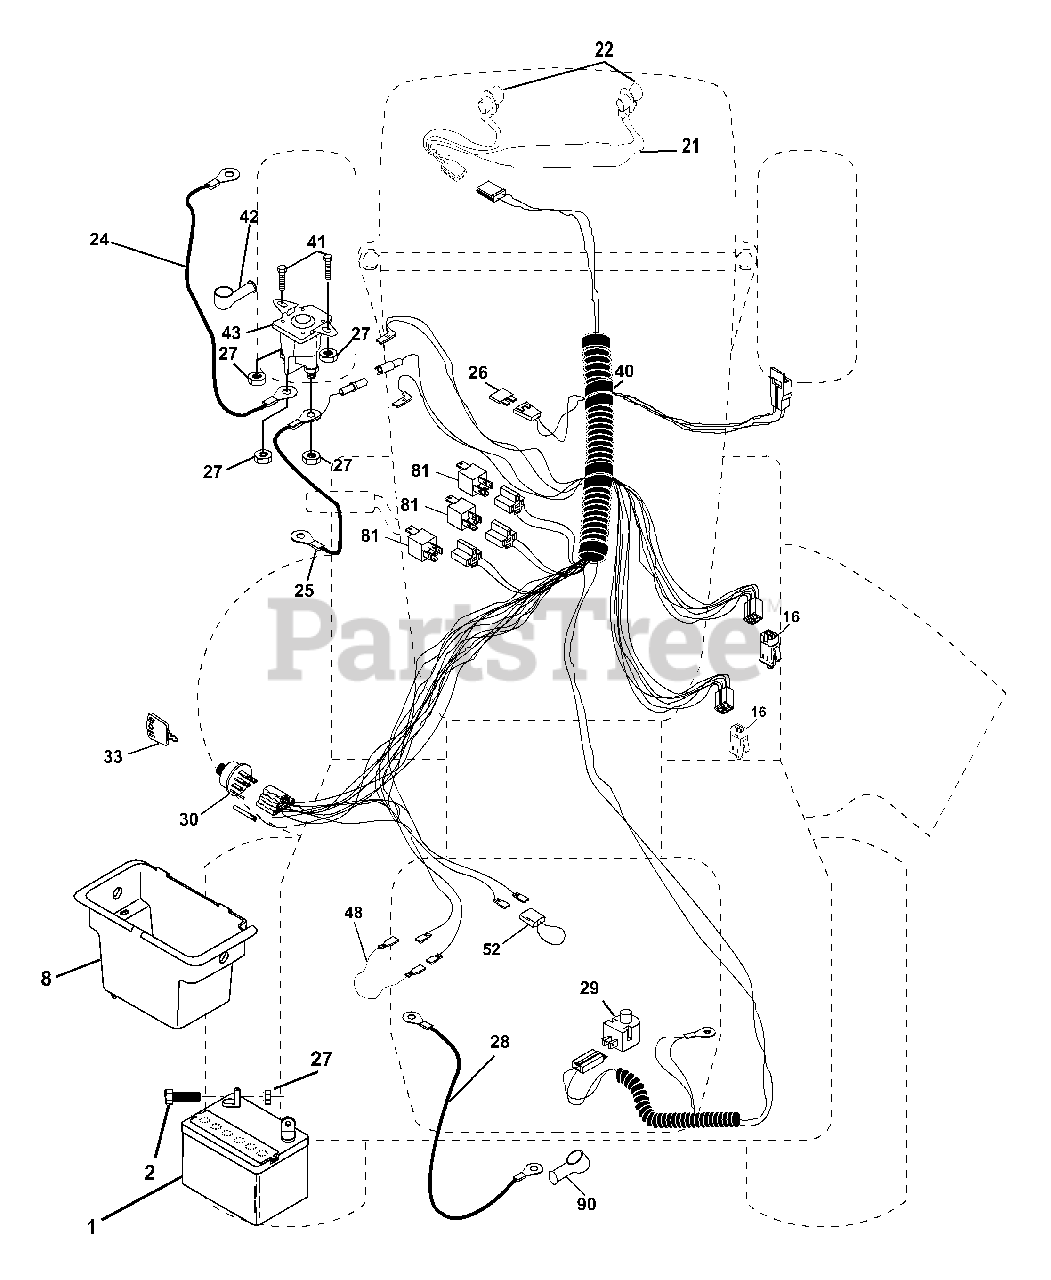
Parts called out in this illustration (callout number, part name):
1	Battery
2	Bolt Hex Hd 1/4-20unc X 3/4
8	Box Battery
16	Switch Interlock
21	Harness Asm Light W/4152j
22	Bulb Light #1156
24	Cable Battery 6 Ga 11" red
25	Cable Battery 6 Ga 44" red w/16 wire
27	Nut Keps Hex 1/4-20 Unc
28	Cable Ground 6 Ga 12" black
29	Switch Plunger Olive
30	Switch Ign Delta
33	Key Ign Molded Generic
40	Harness Ign.
41	Bolt Blk Fin Hex 1/4 - 20 x 1/2
42	Cover Terminal Red
43	Solenoid
48	Adapter Ammeter Rectangular
52	Protection Wire Loop
81	Relay Asm.
90	Cover Terminal Battery
